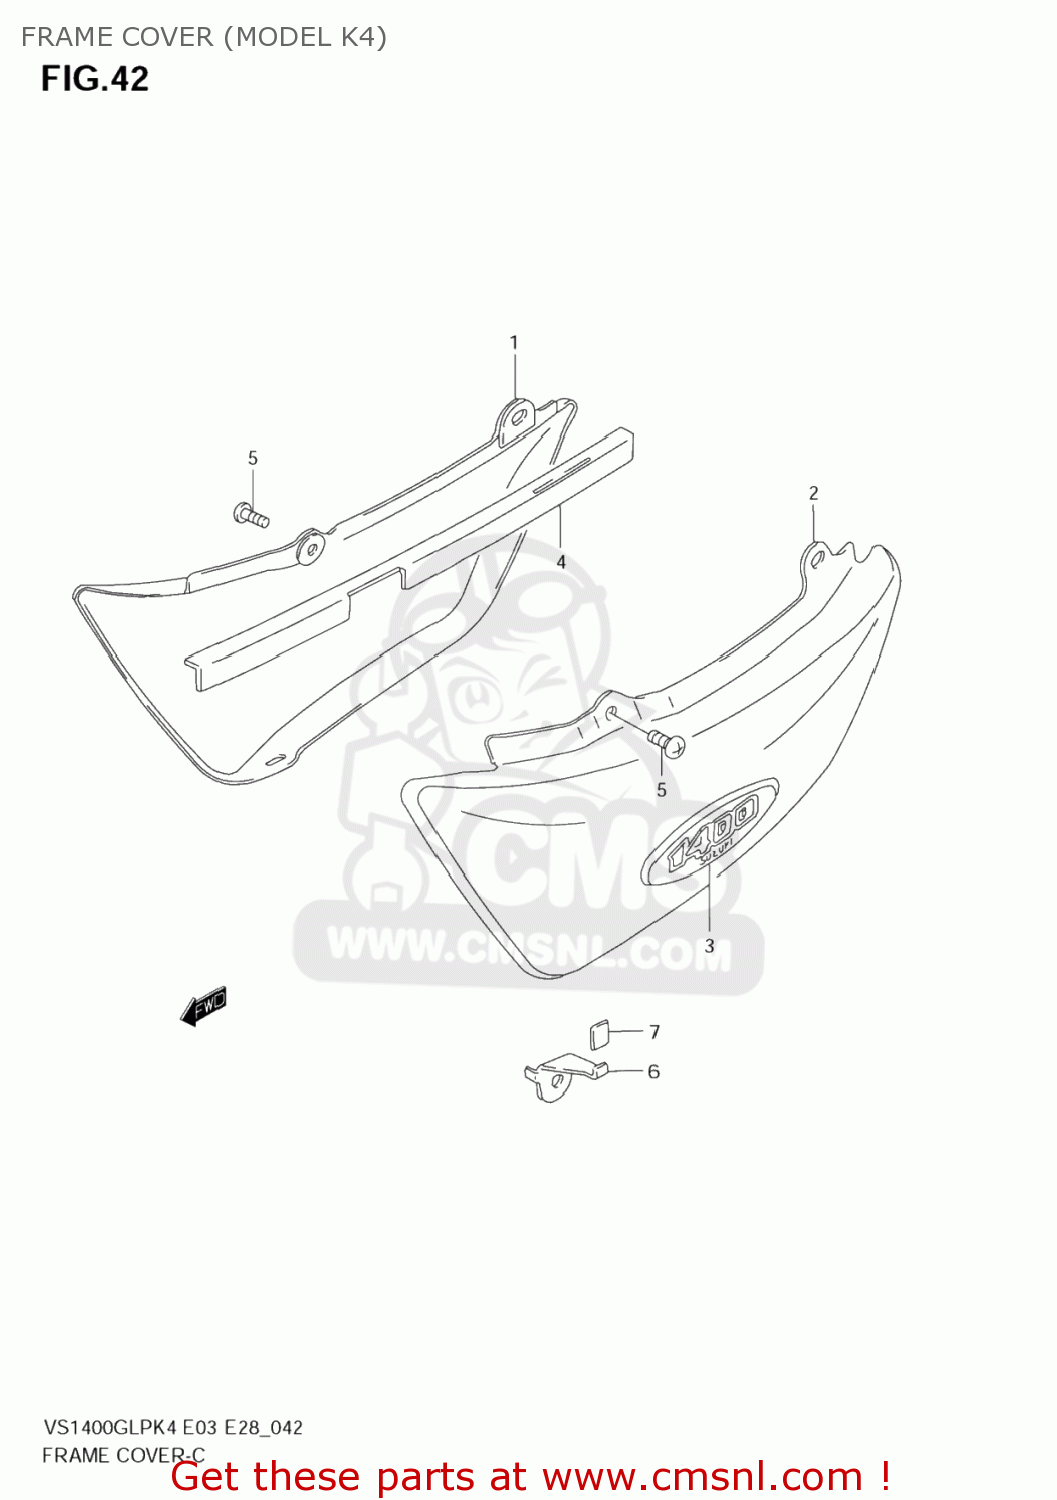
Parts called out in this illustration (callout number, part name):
1	COVER,FRAME,R(BLACK)
2	COVER,FRAME,L(BLACK)
3	EMBLEM,FRAME COVER
4	PROTECTOR,FRAME COVER,R
5	SCREW 6X12
6	HOOK,FRAME COVER,L
7	CUSHION,FRAME COVER HOOK
